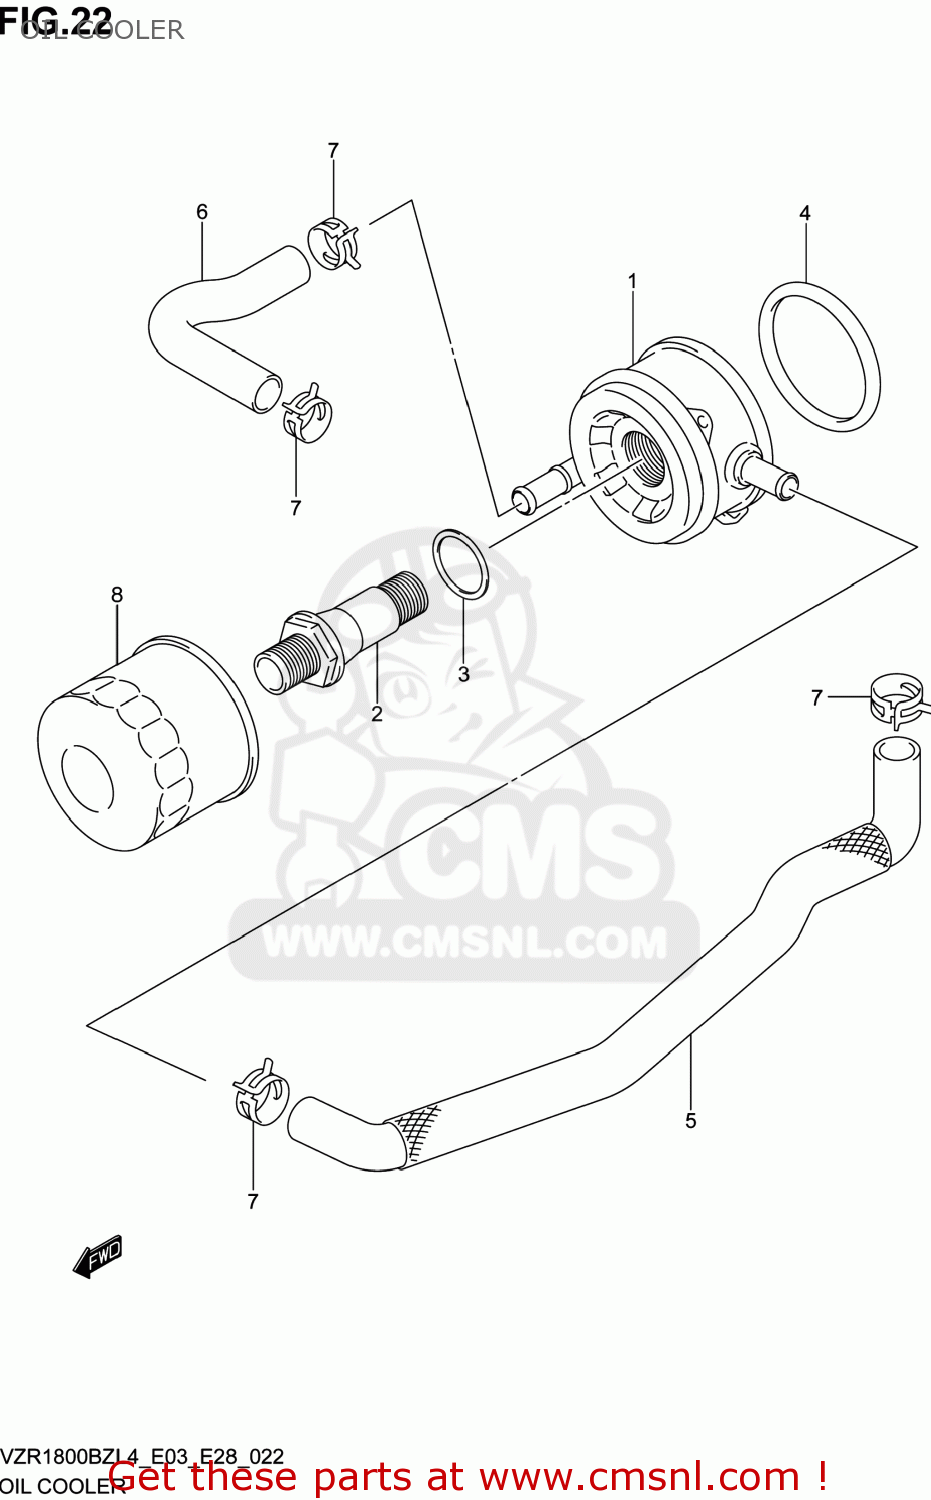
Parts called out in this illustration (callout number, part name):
1	COOLER ASSY,OIL
2	BOLT,OIL COOLER UNION
3	SHIM(25X34X0.7)
4	O RING(D:3.1,ID:63.9)
5	HOSE,OIL COOLER WATER INLET
6	HOSE,OIL COOLER WATER OUTLET
7	CLIP
8	FILTER ASSY,ENGINE OIL
